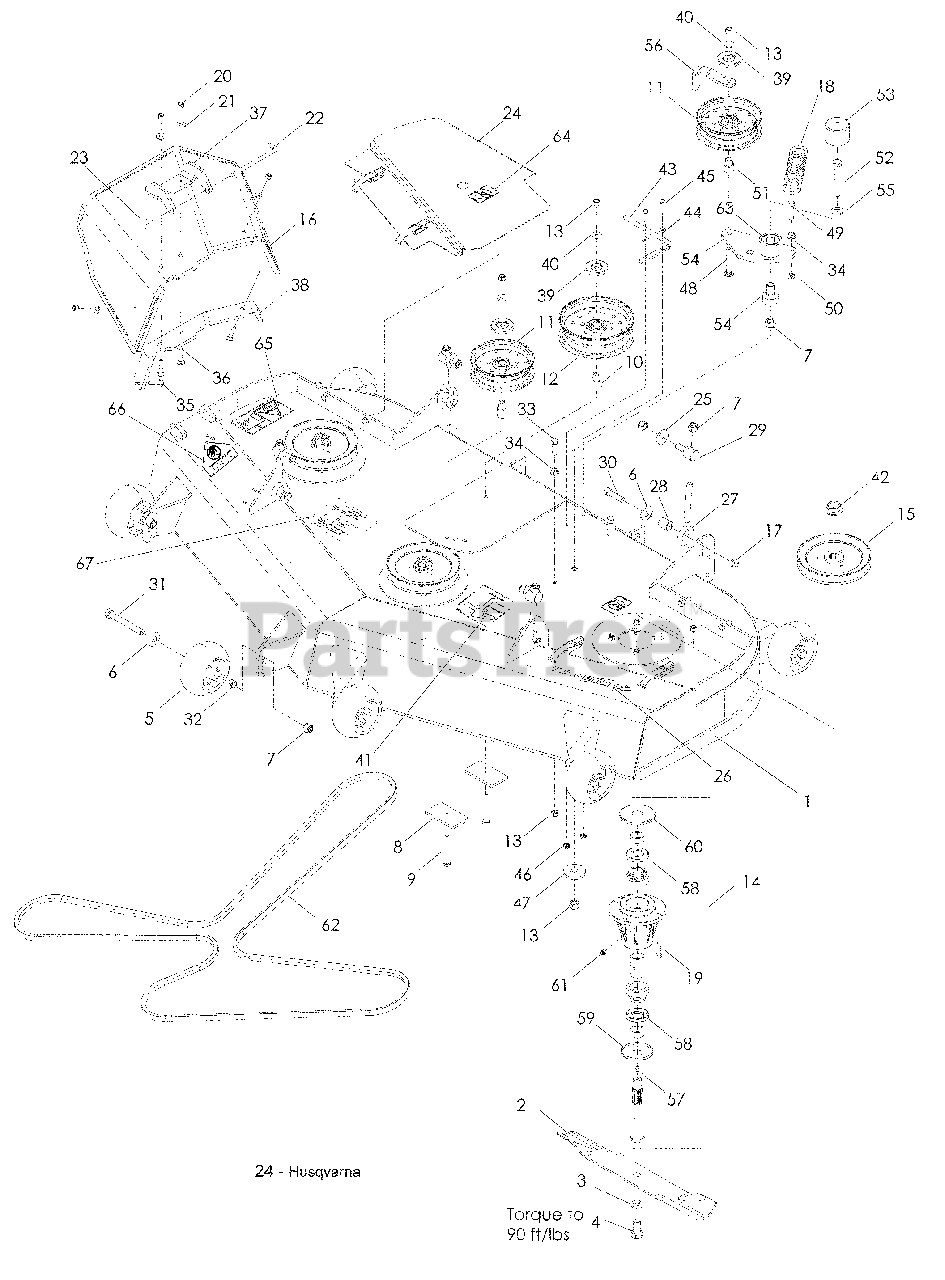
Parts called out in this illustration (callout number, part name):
1	DECK w/DECALS
2	BLADE, 21"
3	WASHER 5/8 SLW
4	HCS 5/8-18 x 1¼
5	WHEEL, GAUGE
6	WASHER ½ FLAT
7	NUT ½-13 NYLOC
8	PAD, PAINTED
9	HCS 3/8-16 x 3
10	BUSHING, IDLER
11	PULLEY, IDLER
12	PULLEY, IDLER
13	NUT 3/8-16 HEX NYLOC
14	HOUSING ASSM
16	CHUTE, DISCHARGE
17	NUT 7/16-14 HEX CTRLK GR A
19	HCS 5/16-18 x 1¼
20	NUT 5/16-18 HEX NYLOC
21	WASHER 5/16 STD FLT
22	PIN, CHUTE PIVOT
23	COTTER PIN 1/8 x ¾
24	BELT SHIELD ASSM RT
25	WASHER ½ STD FLT
26	DECAL, TUNNELRAM
30	HCS 7/16-14 x 1¾
31	HHB ½-13 x 4
32	NUT ½-13 HEX
33	HCS 3/8-16 x 1¼
34	NUT 3/8-16 HEX WHIZLK
35	RHSNB 5/16-18 x 1¼
36	RHSNB 5/16-18 x 1½
37	BRACKET, MOUNTING
38	REINFORCEMENT, 52-61
39	SHIELD, DUST
40	WASHER 3/8 SPECIAL
41	DECAL, BELT ROUTING
42	NUT ¾-16 FLANGE
43	GUIDE, BELT
44	WASHER ½ STD FLT
45	HCS ¼-20 x 1
46	NUT ¼-20 HEX FLANGE
47	WASHER, SUPPORT
48	RHSNB 3/8-16 x 2¾
49	HCS 3/8-16 x 1½ GR 8
50	NUT 3/8-16 HEX JAM
51	BUSHING, IDLER
52	HCS ½-13 x 3¼
53	CAP, VINYL
54	BEARING, PIVOT
55	WASHER, BELLEVILLE
56	GUIDE, BELT
58	SEAL, SHAFT
59	DUST CAP, BOTTOM
60	DUST CAP, TOP
61	POPPET, GREASE
62	BELT, DECK
63	ARM, IDLER w/ BEARINGS
64	DECAL, NO STEP
65	DECAL, SEVERING
66	DECAL, WARNING
67	DECAL, ANTI-SCALP
